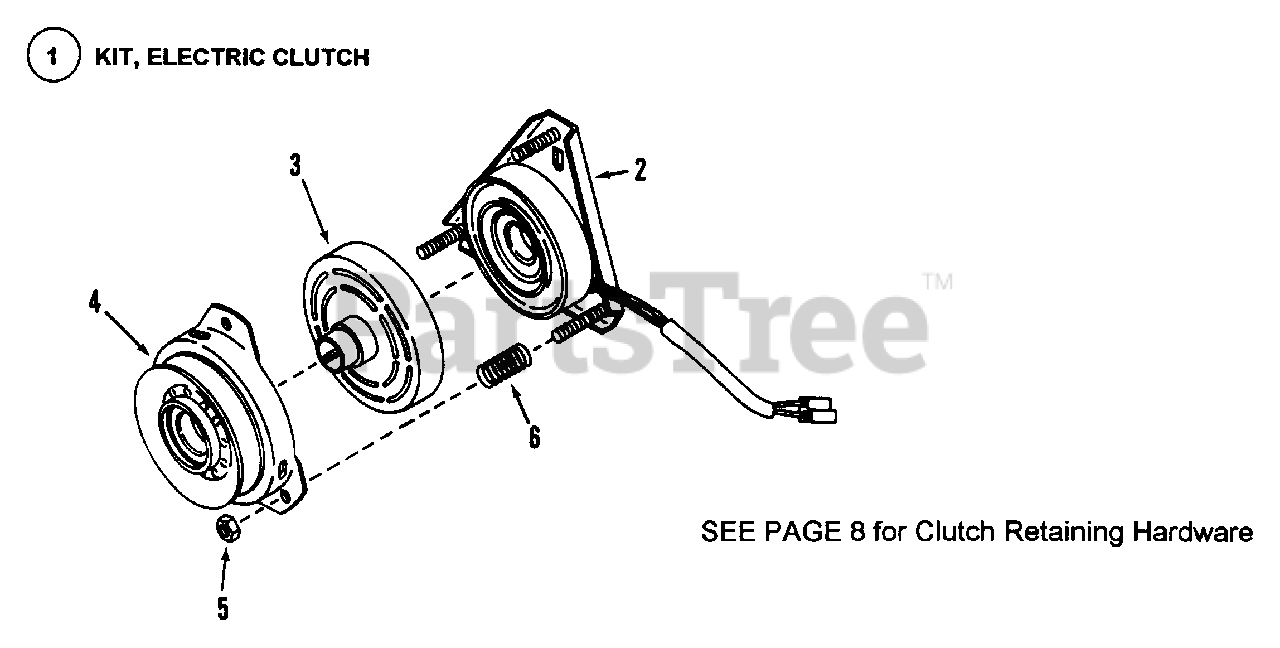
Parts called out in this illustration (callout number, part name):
1	KIT, Electric Clutch
2	FIELD COIL
3	ROTOR
4	ASSEMBLY, Arm-Pulley
5	NUT, 3/8-24 Hex Nylok
6	COIL SPRING
